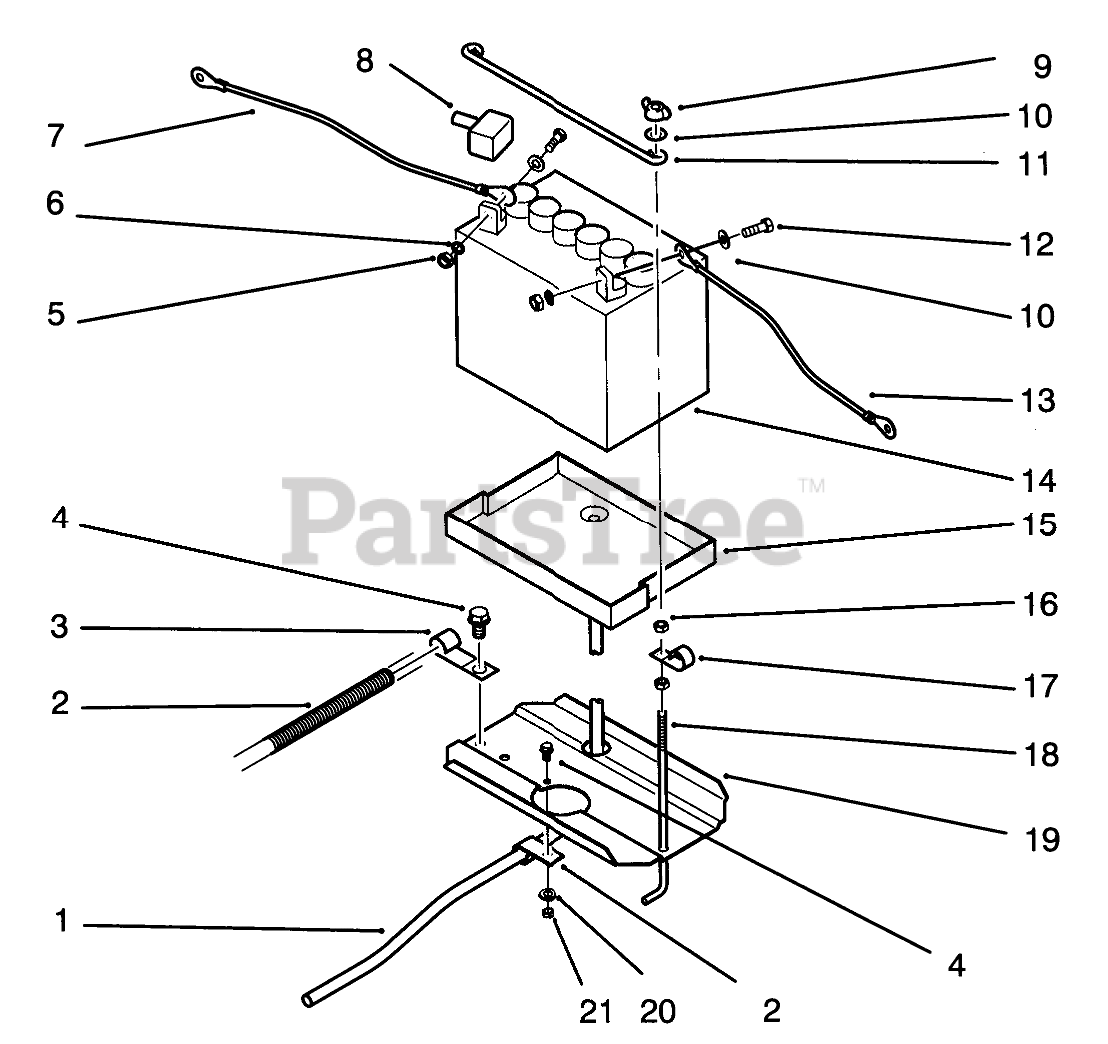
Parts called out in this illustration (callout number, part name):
1	TUBE-21" BATTERY DRAIN
2	WIRING-HARNESS & DIA
3	CLIP
4	Screw
5	NUT-HEX
6	WASHER-LOCK
7	WIRE - 14" BLACK
8	Boot
9	NUT-WING
10	WASHER-FLAT
11	ROD-BATTERY HOLD DWN
12	SCREW-HH
13	ASS'Y-WIRE
14	Battery
15	TRAY-BATTERY
16	Nut
17	CLAMP
19	Tray
20	WASHER-FLAT
21	NUT-LOCK, NI
